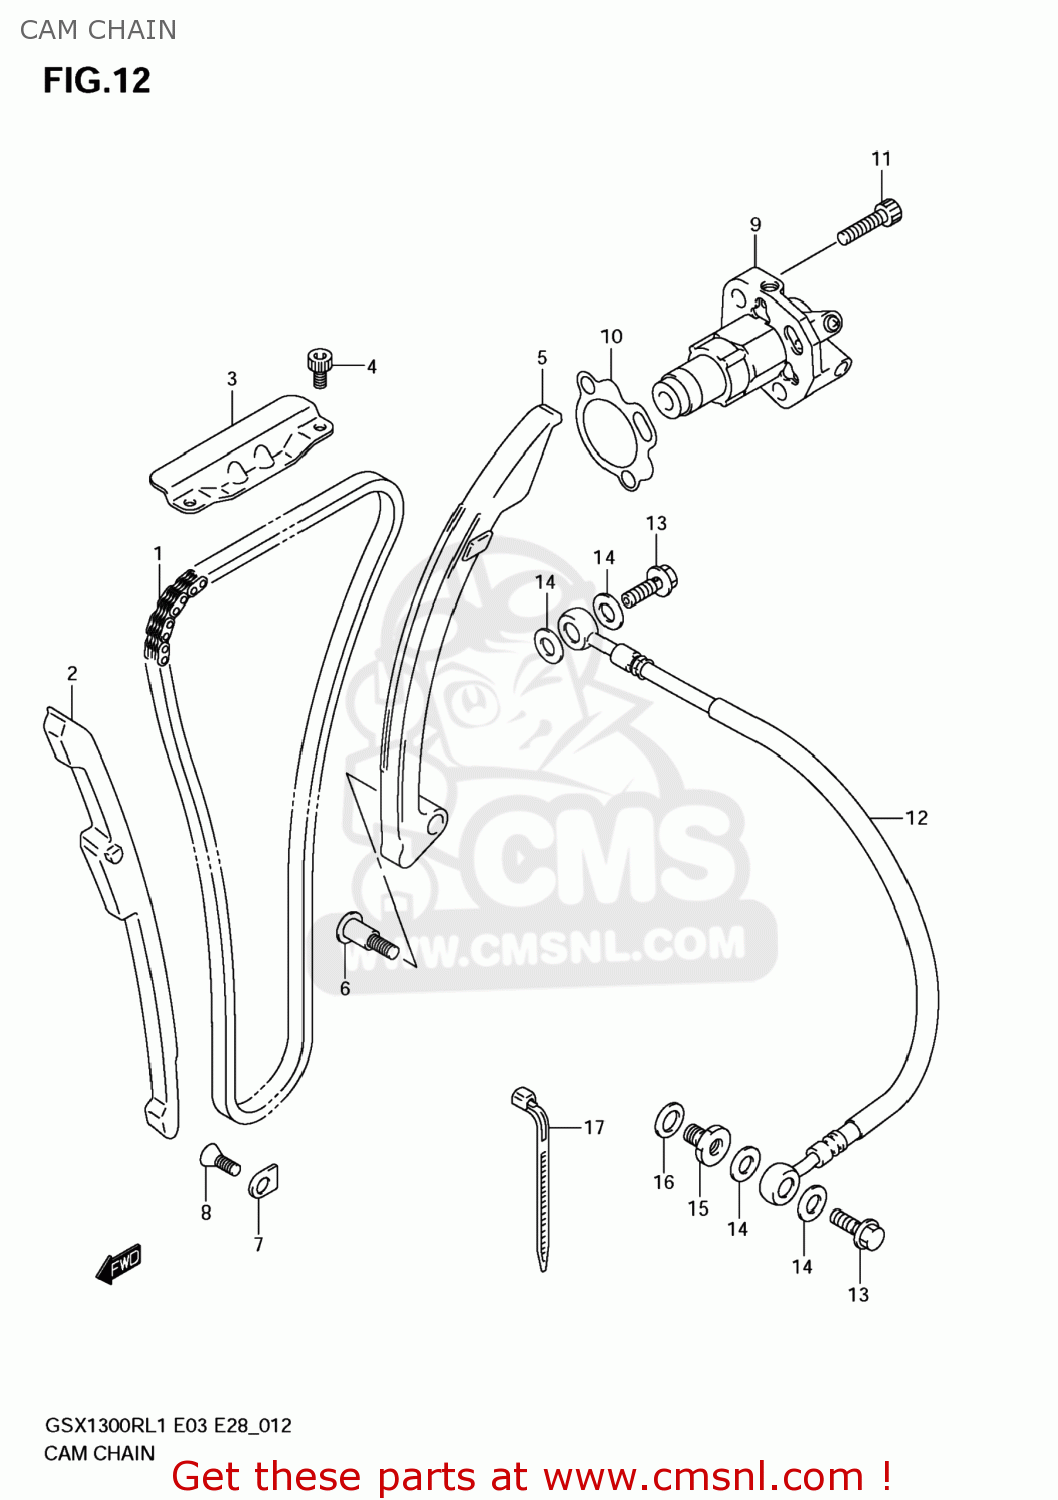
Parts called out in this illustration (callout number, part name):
1	CHAIN,CAMSHAFT DRIVE
2	GUIDE,CAM CHAIN NO.1
3	GUIDE,CAM CHAIN NO.2
4	BOLT
5	TENSIONER,CAM CHAIN
6	BOLT,CAM CHAIN TENSIONER
7	RETAINER,CAM CHAIN GUIDE NO.1
8	SCREW
9	ADJUSTER ASSY,TENSIONER
10	GASKET,TENSIONER ADJUSTER (NAS)
11	BOLT
12	HOSE,CAM CHAIN TNSN ADJ OIL
13	BOLT,ADJ OIL HOSE UNION
14	GASKET(7.8X13.5X1.2) (NAS)
15	PLUG,ADJ OIL HOSE UNION
16	GASKET(13.8X18.8X4.8) (NAS)
17	CLAMP(L:165)
